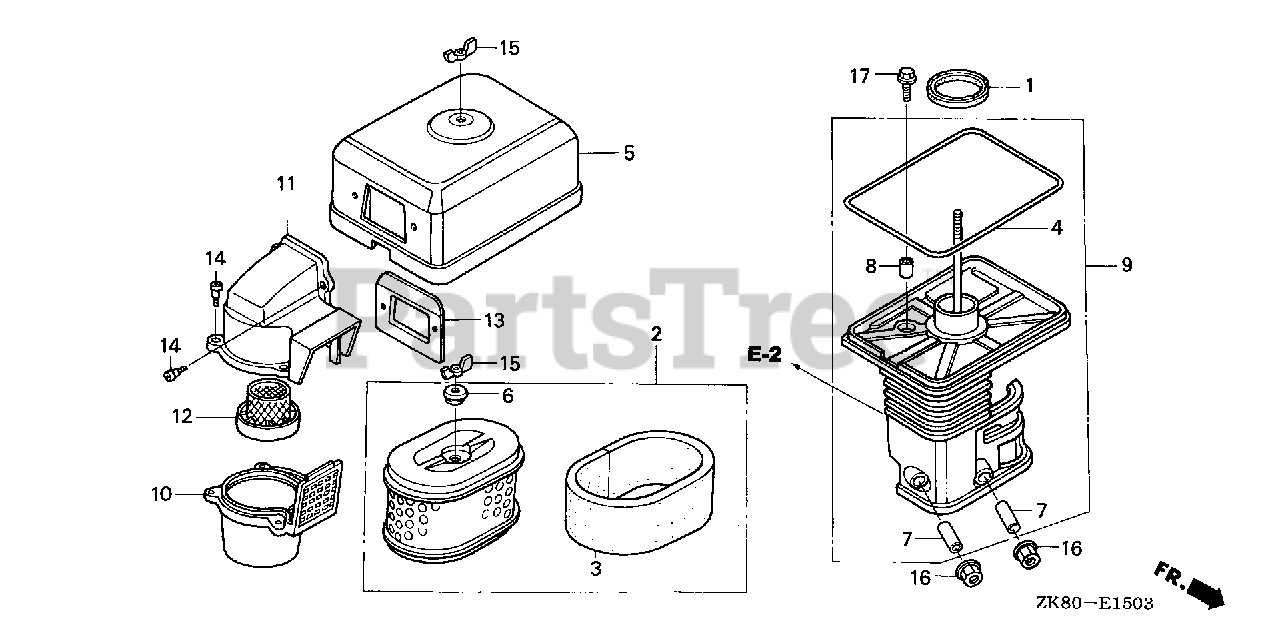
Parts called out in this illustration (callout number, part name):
1	GASKET, ELBOW
2	ELEMENT, AIR CLEANER (DUAL)
3	FILTER (OUTER)
4	GASKET, AIR CLEANER COVER
5	COVER, AIR CLEANER (DUAL)
6	GROMMET, AIR CLEANER
7	COLLAR, AIR CLEANER
8	COLLAR B, AIR CLEANER
9	ELBOW, AIR CLEANER
10	CASE, PRE AIR CLEANER
11	CAP, PRE AIR CLEANER
12	GUIDE, PRE AIR CLEANER
13	PLATE, PRE AIR CLEANER
14	BOLT, SPLASH GUARD
15	NUT, TOOL BOX SETTING
16	NUT, FLANGE (6MM)
17	BOLT, FLANGE (6X20)
